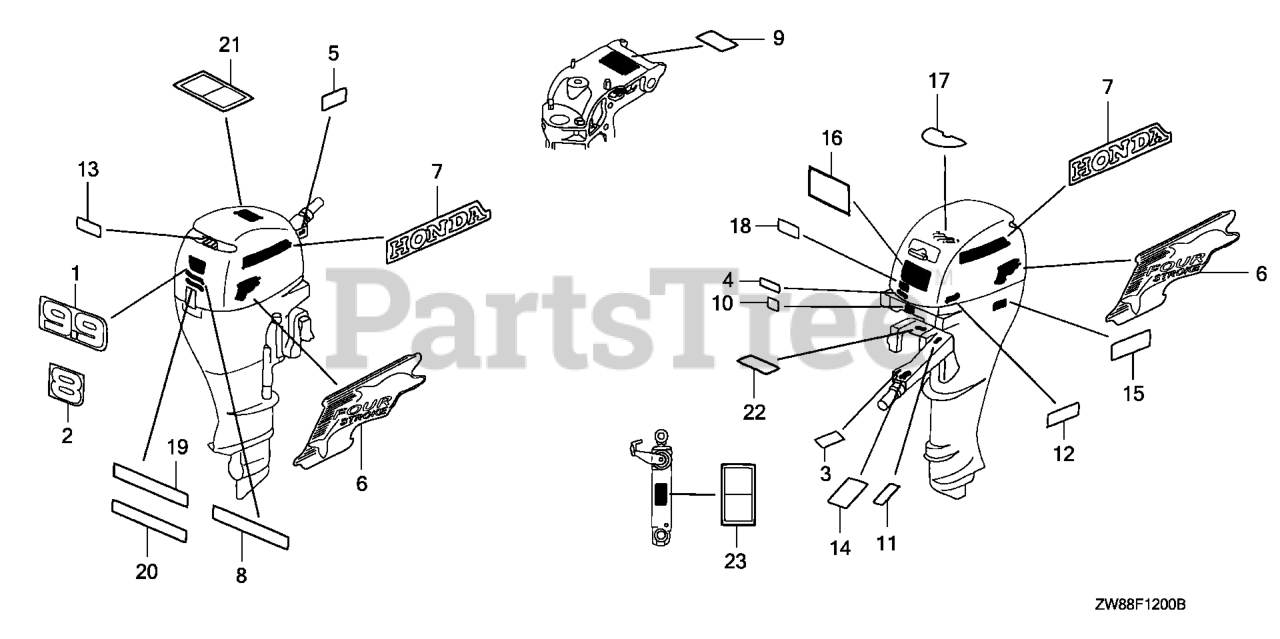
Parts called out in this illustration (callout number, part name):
1	MARK, RR. (9.9)
3	MARK, EMERGENCY SWITCH INDICATION
4	MARK, SPARE CLIP (ENGLISH)
6	MARK, SIDE
7	MARK, SIDE STRIPE (HONDA)
8	MARK, POWER THRUST
9	LABEL, SPECIFICATION
10	MARK, OIL PRESSURE
11	MARK, CHANGE (JAPANESE/ENGLISH)
12	MARK, RECEPTACLE (6A)
13	LABEL, OIL CAUTION (ENGLISH)
14	MARK, THROTTLE (ENGLISH)
15	LABEL, STORING CAUTION (ENGLISH)
16	LABEL, CAUTION OPERATOR (ENGLISH)
17	MARK, EMERGENCY STARTER (ENGLISH)
18	MARK (E-SPEC)
